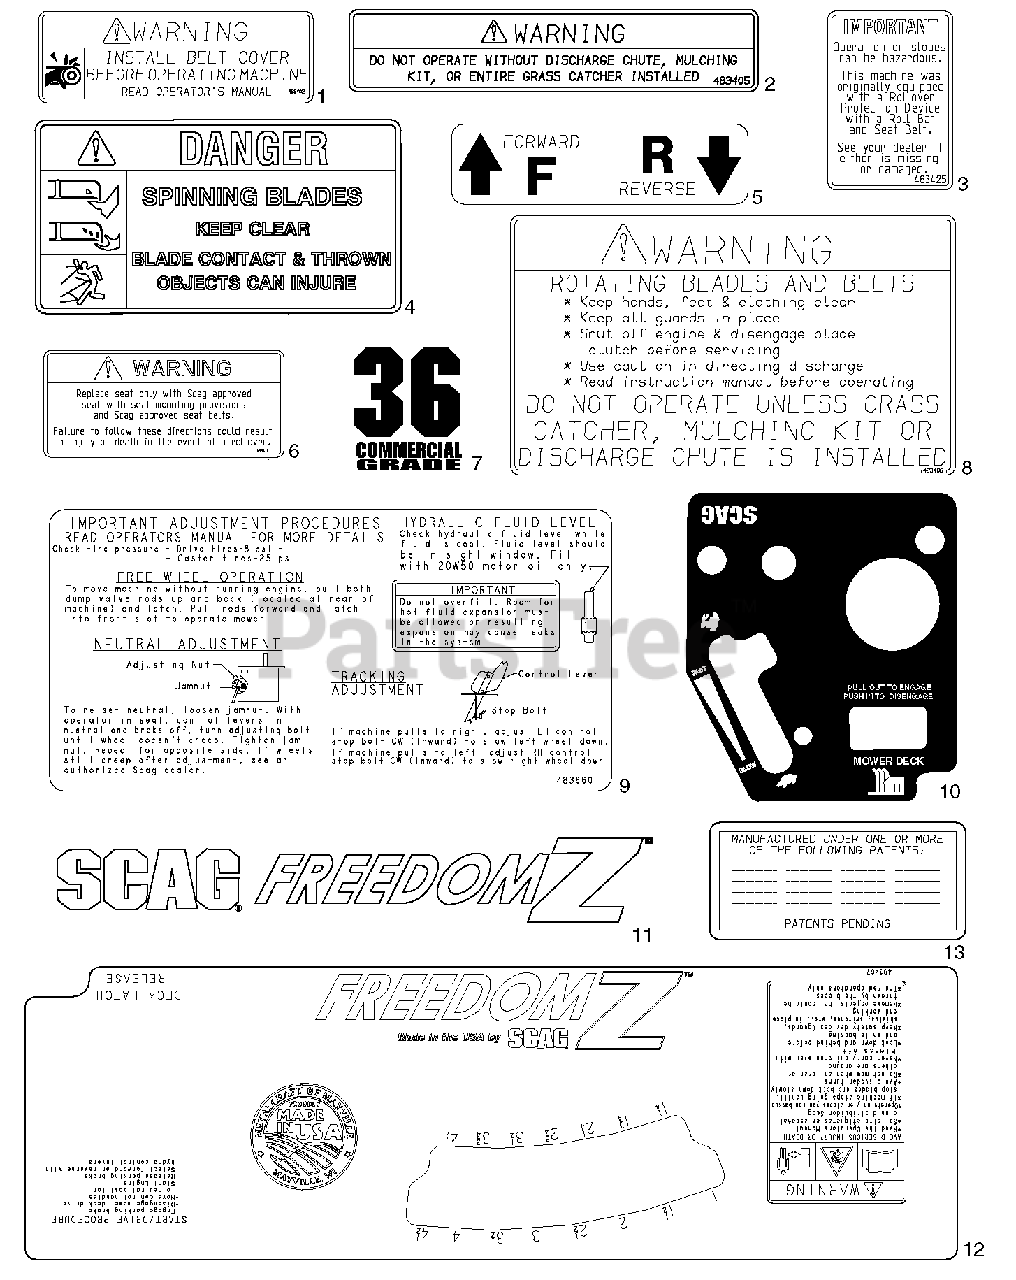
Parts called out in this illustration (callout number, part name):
1	Decal, Belt Cover
2	Decal, Warning
3	Decal, ROPS
4	Decal, Spinning Blades
5	Decal, Traction Control
6	Decal, Seat Replacement
7	Decal, 36 Commercial
7	Decal, 48 Commercial
7	Decal, 52 Commercial
7	Decal, 61 Commercial
8	Decal, Knives
9	Decal, Adjustment SFZ
10	Decal, Instrument Panel - SFZ36
10	Decal, Instrument Panel - SFZ48, SFZ52 & SFZ 61
11	Decal, Front SFZ
12	Decal, Cutting Height
13	Decal, Patent
